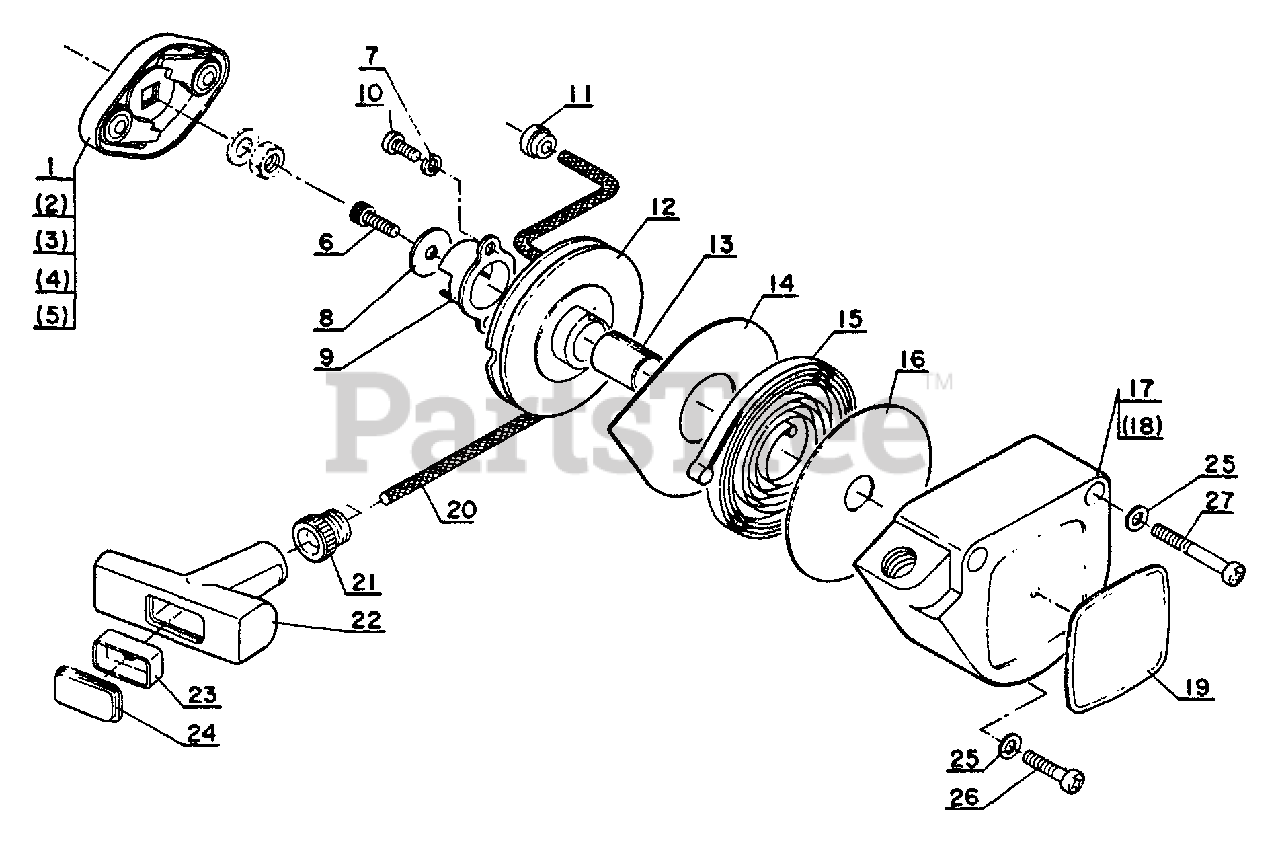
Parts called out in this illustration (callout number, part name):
1	STARTER PAWL ASSY
6	SCREW - 4X12
7	LOCKWASHER - 4
9	CATCHER, PAWL
10	SCREW - 4X8
11	RETAINER, ROPE
12	REEL, ROPE
13	BUSHING
14	PLATE, STARTER
15	SPRING, REWIND
16	PLATE, STARTER
17	CASE, STARTER
19	NAME PLATE
20	ROPE, STARTER - 3.5X850
21	GUIDE, ROPE
22	GRIP, STARTER
23	RING, RETAINING
25	WASHER - 4
26	SCREW - 4X20
27	SCREW - 4X35
